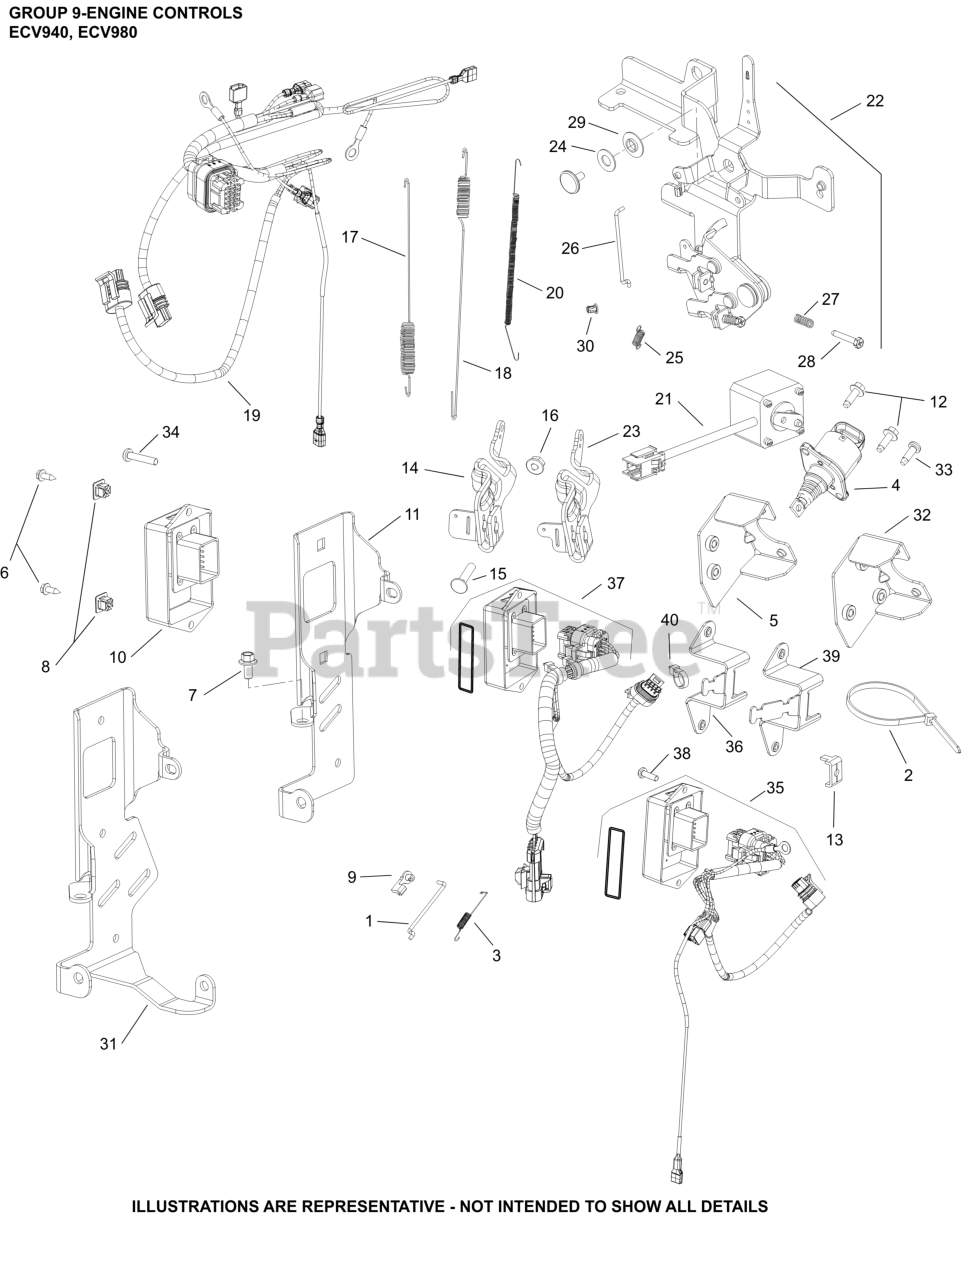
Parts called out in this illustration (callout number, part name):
1	LINKAGE, THROTTLE EFI, VERTICAL
7	SCREW, FLG M6X1.0X12
9	BUSHING, THROTTLE LINKAGE
15	BOLT, RD HD SQ NECK M6X1.0X25
16	NUT, FLG M6X1.0
17	SPRING, GOV (IDLE 1400-1625)
17	SPRING, GOVERNOR
20	SPRING, LINKAGE
22	CONTROL ASSY SPEED (VERTICAL) EFI
23	KIT, GOVERNOR LEVER
24	WASHER, FLAT 9 MM
25	SPRING, RETURN
26	LINKAGE, THROTTLE LEVER
27	SPRING, SPEED CONTROL (SHORT)
28	SCREW, PHL THD FRM M4X0.7X25
29	WASHER, NYLON SHOULDER
